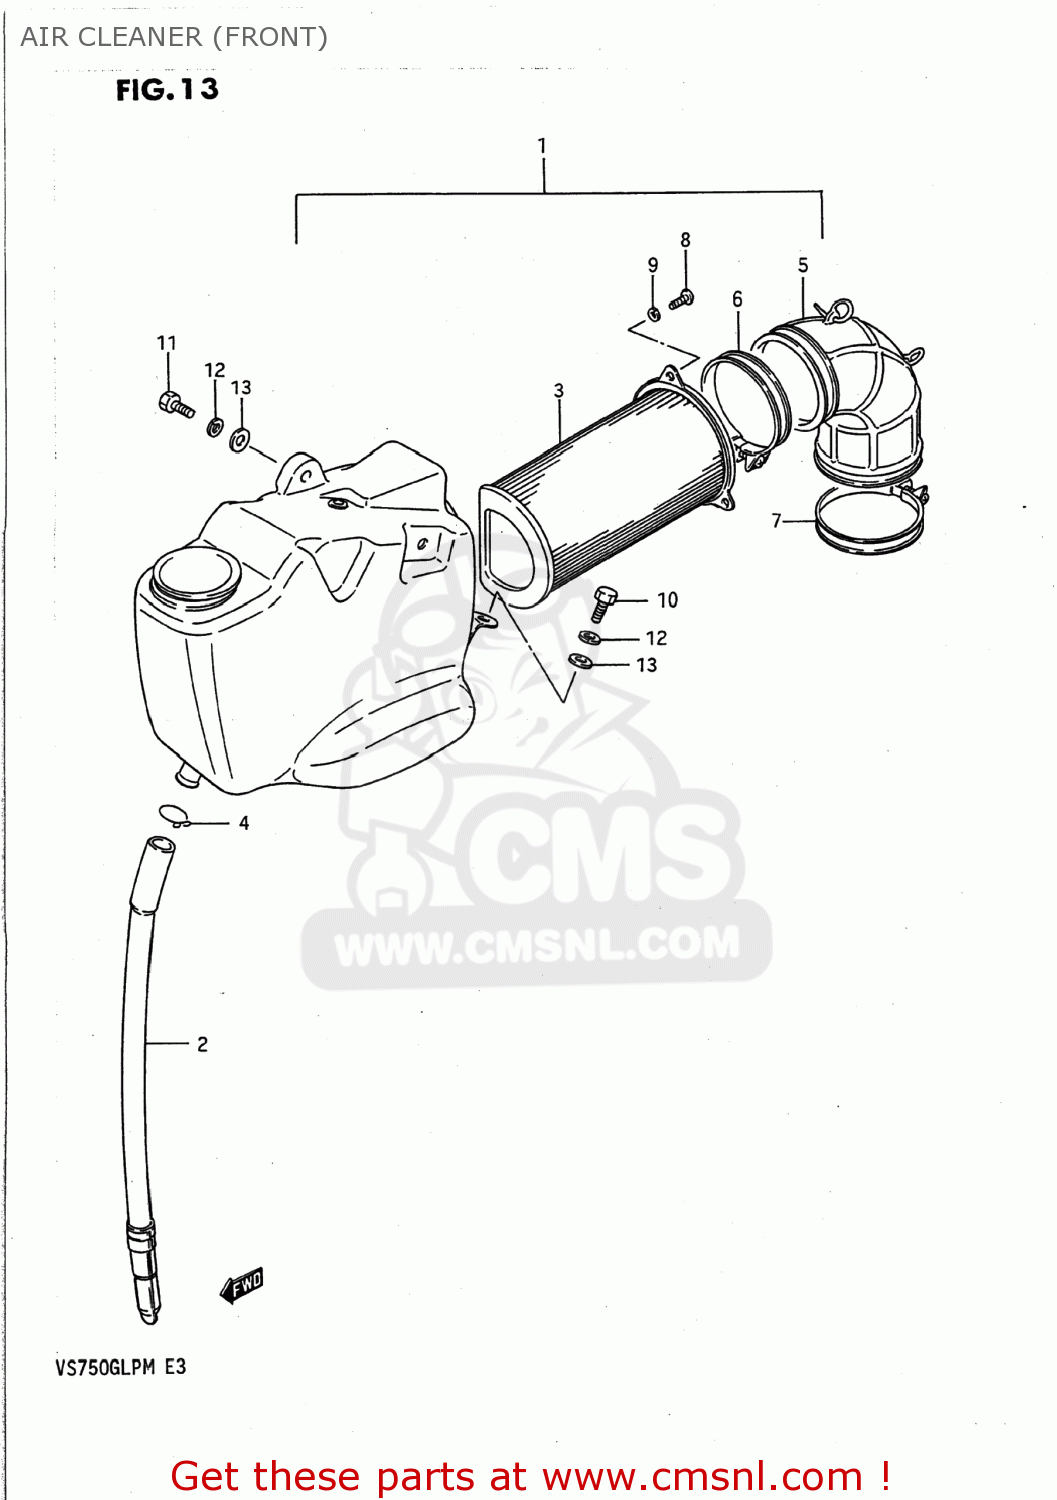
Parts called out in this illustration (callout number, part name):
1	CLEANER ASSEMBLY,AIR
2	DRAIN TUBE
3	FILTER,AIR CLEANER
4	CLIP
5	TUBE,AIR CLEANER OUTLET
6	CLAMP
7	CLAMP
8	SCREW
9	LOCK WASHER
10	BOLT
11	BOLT
12	WASHER,LOCK
13	WASHER
